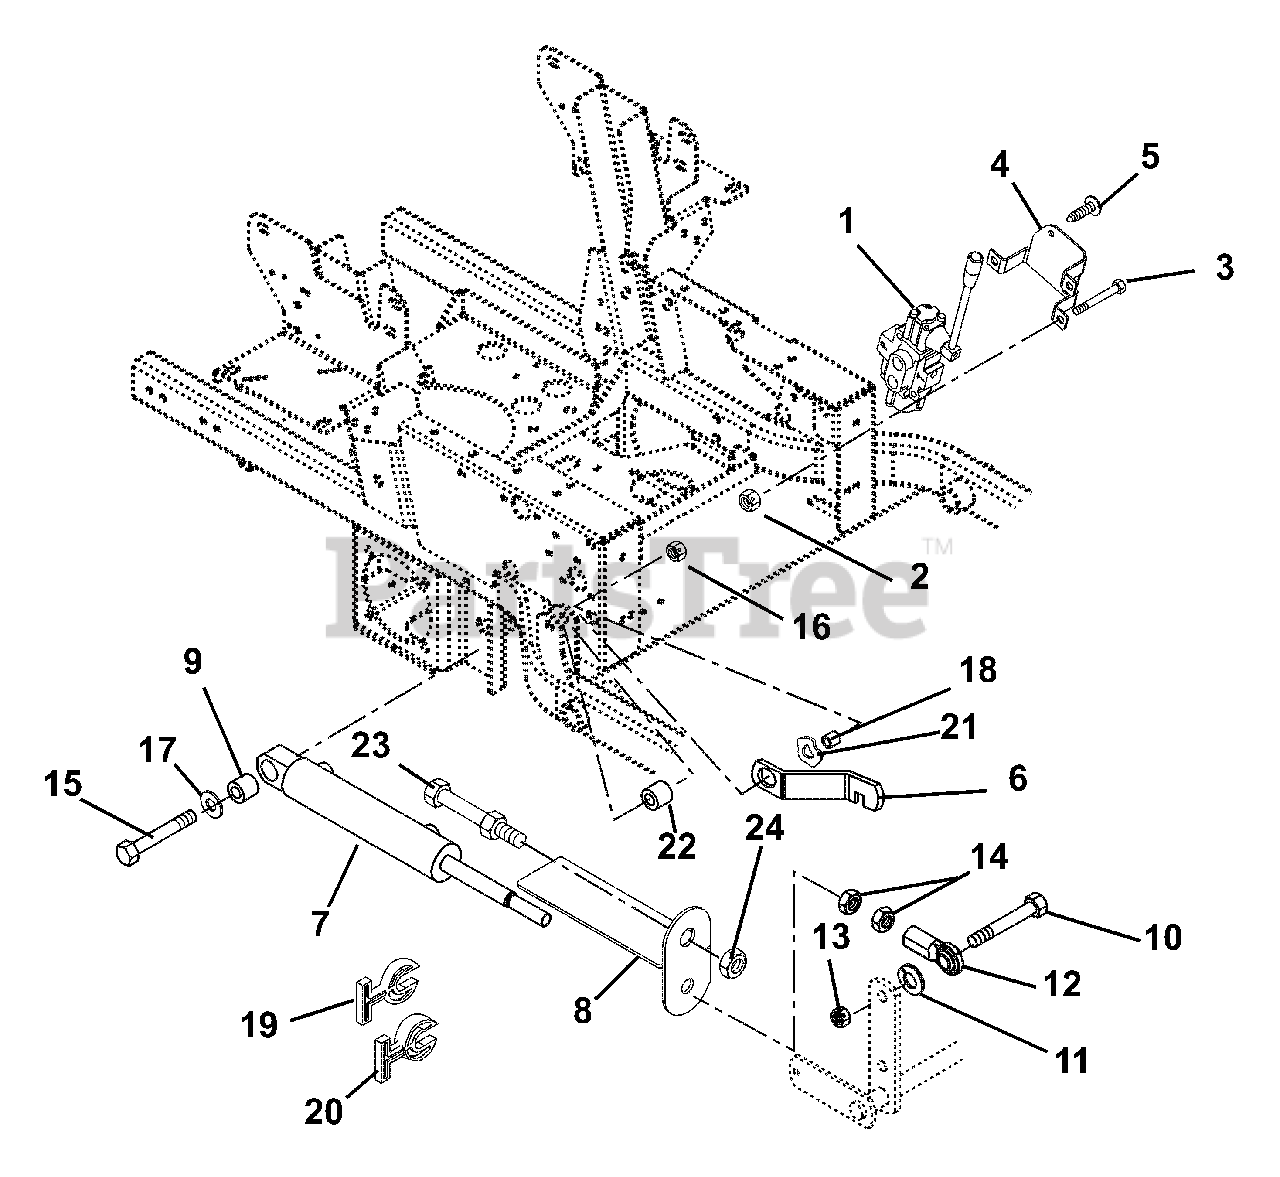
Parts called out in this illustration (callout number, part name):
1	VALVE, HYDRAULIC
2	@NUT-LK-TOP-FLG .31-18 YWZC
3	@BLT-HEX .31-18X2.50 GR5 YWZC
4	VALVE MOUNTING BRACKET -BLACK
5	@SCR-TAP .38-16X.50 HWH TR YWZ
7	CYLINDER - HYDRAULIC LIFT
8	CUT INDICATOR/GUARD - BLACK
9	BUSHING, .516X1.000X1.050 LG
10	BLT-HEX .62-11X2.25 YWZC GR8
11	@WSHR-LK .62X.156 REG YWZC
12	ROD END, 5/8 RH - FEMALE
13	@NUT-LK-CTR .62-11 YWZC
14	NUT-JAM .625-18 YWZC
15	@BLT-HEX .50-13X3.50 GR5 YWZC
16	@NUT-LK-TOP-FLG .50-13 YWZC
17	WSHR-FL-STL .515X1.625X.250 YZ
18	BSHG-FLG .515X.750X.285X1.120
19	STOP, CYLINDER .34 THK
20	STOP, CYLINDER .680 THK
21	WASHER-WAVE .760X1.120X.080
22	SPACER .516X1.000X.875
24	NUT-JAM .75-16 YWZC
